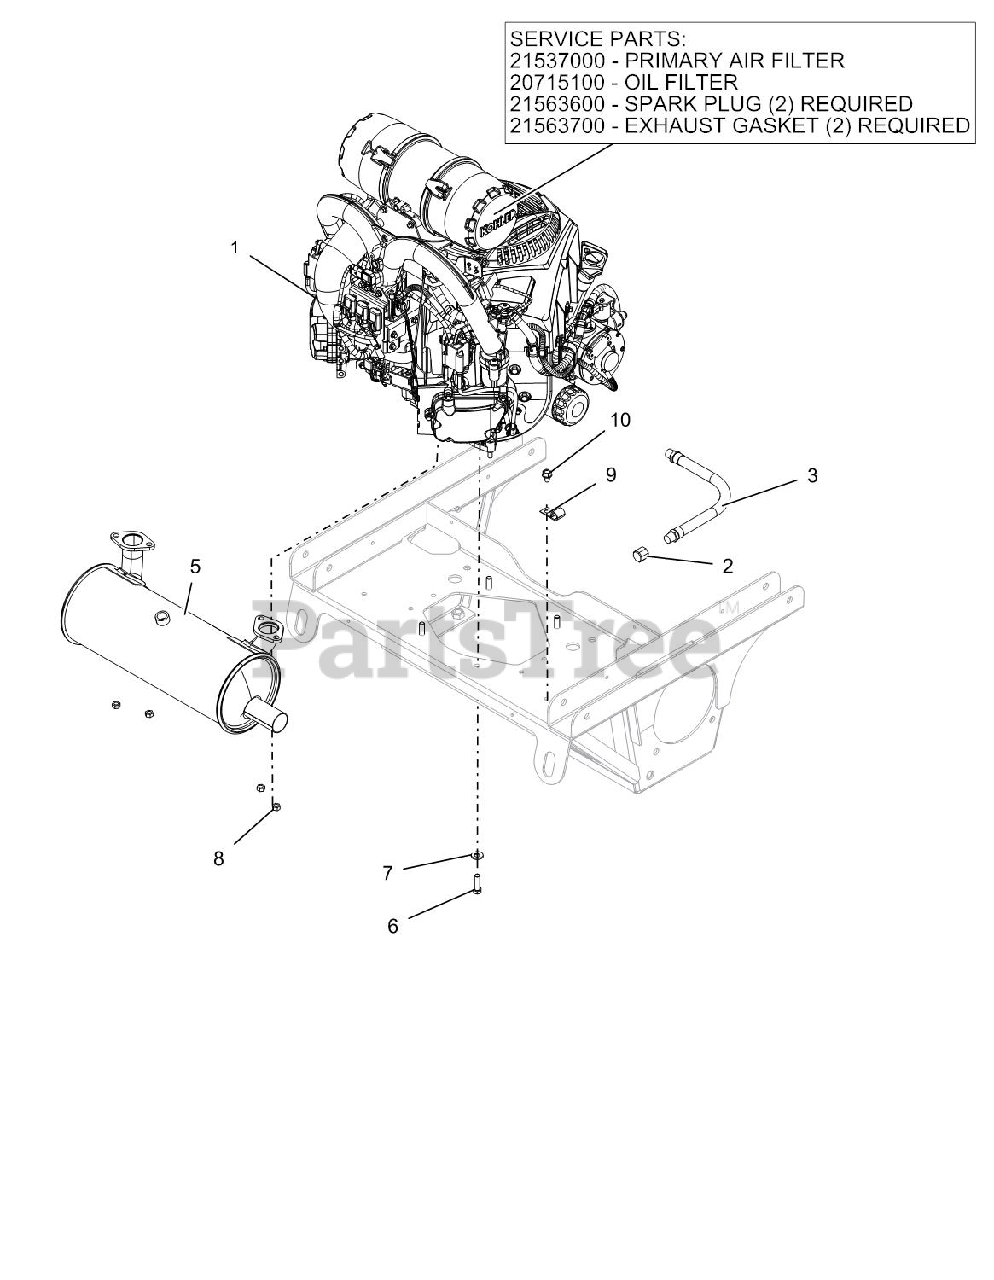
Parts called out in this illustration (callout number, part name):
1	ELEMENT, OUTER PRIMARY
1	OIL FILTER KOHLER
1	PLUG, SPARK
1	GASKET, EXHAUST
1	ENGINE, KOHLER PCV860 EFI LP
2	PIPE CAP 3/8 NPT FEMALE
3	HOSE,HYD .38-14-0K M6N0-M6N0
5	MUFFLER, KOHLER EFI
6	BLT-HEX.38-16X1.25 G5YZ NYTORQ
7	WASHER, 3/8" SPRING DISC
8	NUT-LK-TOP M8-1.25 YWZC
10	SCR-TAP .38-16X.50 HWH TR YWZ
